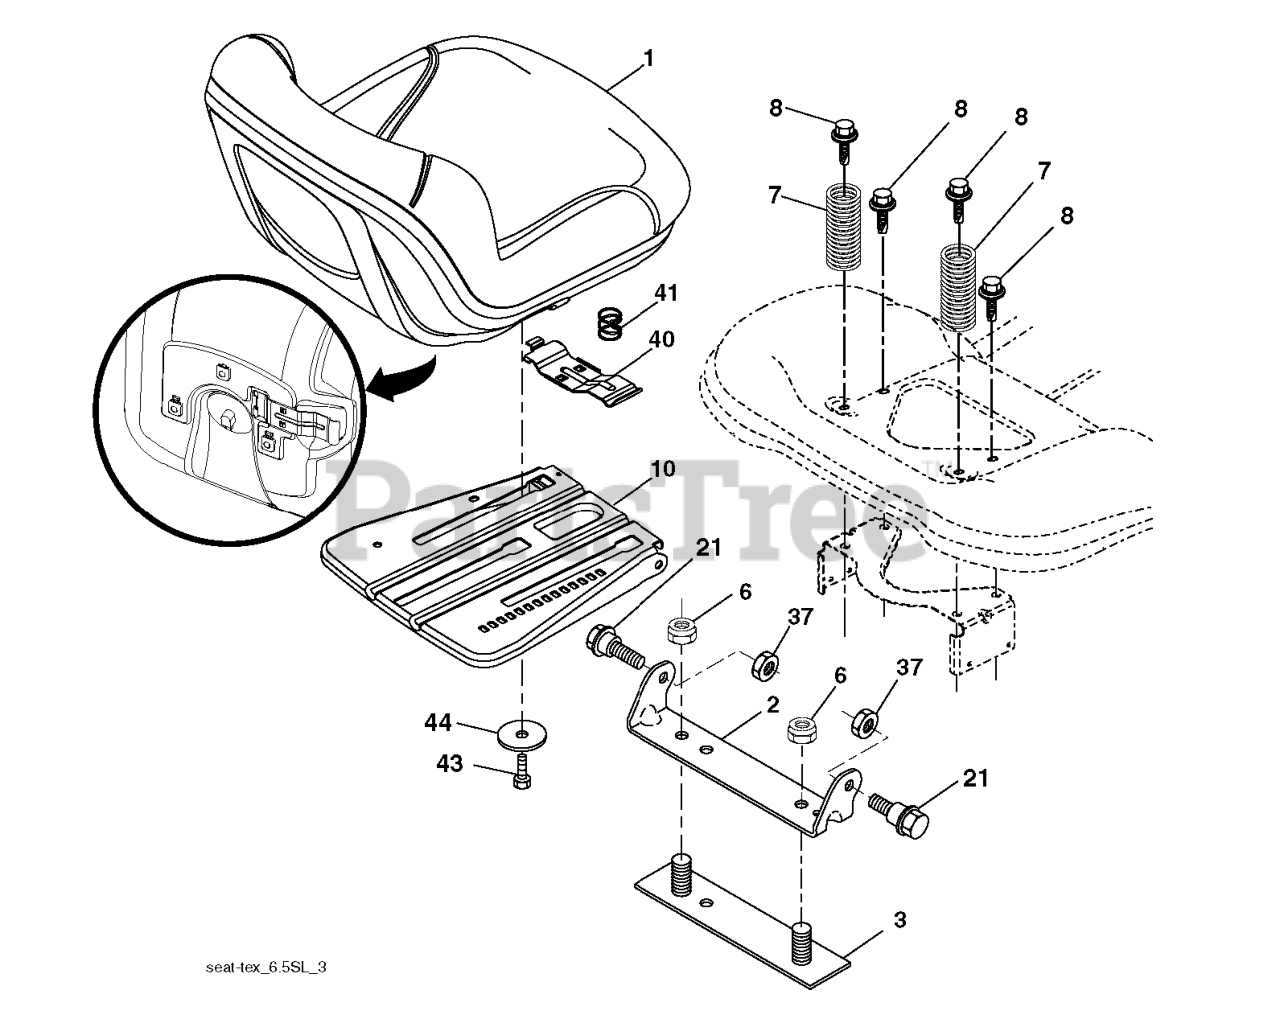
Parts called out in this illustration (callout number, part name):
1	Nut, Keps Blk Hex 1/4-20 UNC
2	CABLE.BATTERY.6GA.16"RED
3	REPL BY 532 12 38-99
5	BRACKET LT
6	SWITCH INTERLOCKT
7	KEEPER, ACTUAT. L.R.
9	KEY MLD GEN DELTA
10	COVER SWITCH KEY
11	NUT, IGNITION
12	IGNITION SWITCH
15	RP.SWITCH.PLUNGER.NC.GRAY
17	FUSE 15 AMP
18	CABLE ASSY
20	NUT
21	LOCKWASHER
22	BOLT
24	TERMINAL COVER
25	REPL BY 532 10 99-46
26	BOLT.HEX.1/4.X.3/4.DICHROMATE
30	NUT
36	Washer, Lock, Internal Tooth 1/4
55	Screw 5/16-18 x 1/2 Hex, Self Tapping 5/16-18 x 1/2
70	ENGINE HARNESS
